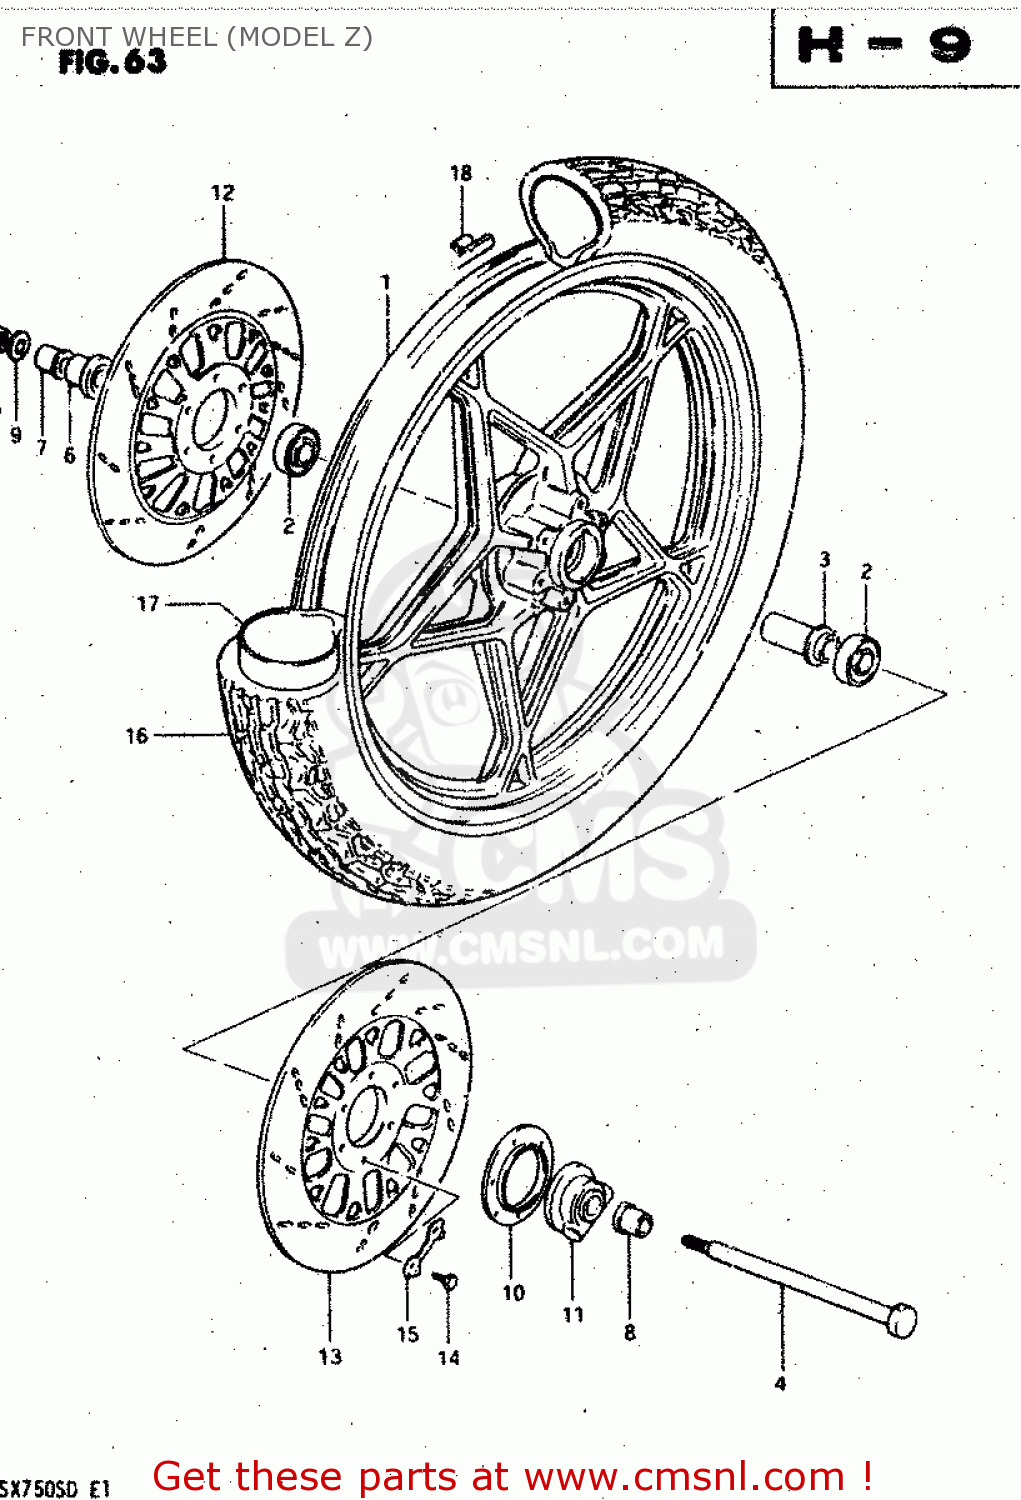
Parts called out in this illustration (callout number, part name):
1	WHEEL, FRONT (19X1.85) (GRAY)
2	BEARING
3	SPACER,FR HUB BEARING
4	AXLE,FR
5	NUT
6	SPACER,FR AXLE,R
7	SPACER,FR AXLE,R
8	SPACER,FR AXLE,L
9	WASHER
10	DUST SEAL,SPEEDOMETER GEAR BOX
11	BOX ASSEMBLY,SPEEDOMETER GEAR
12	DISC,FR BRAKE,R
13	DISC,FR BRAKE,L
14	BOLT(8X25)
15	WASHER
16	TIRE,FRONT
17	TUBE,INNER
18	BALANCER,WHEEL
